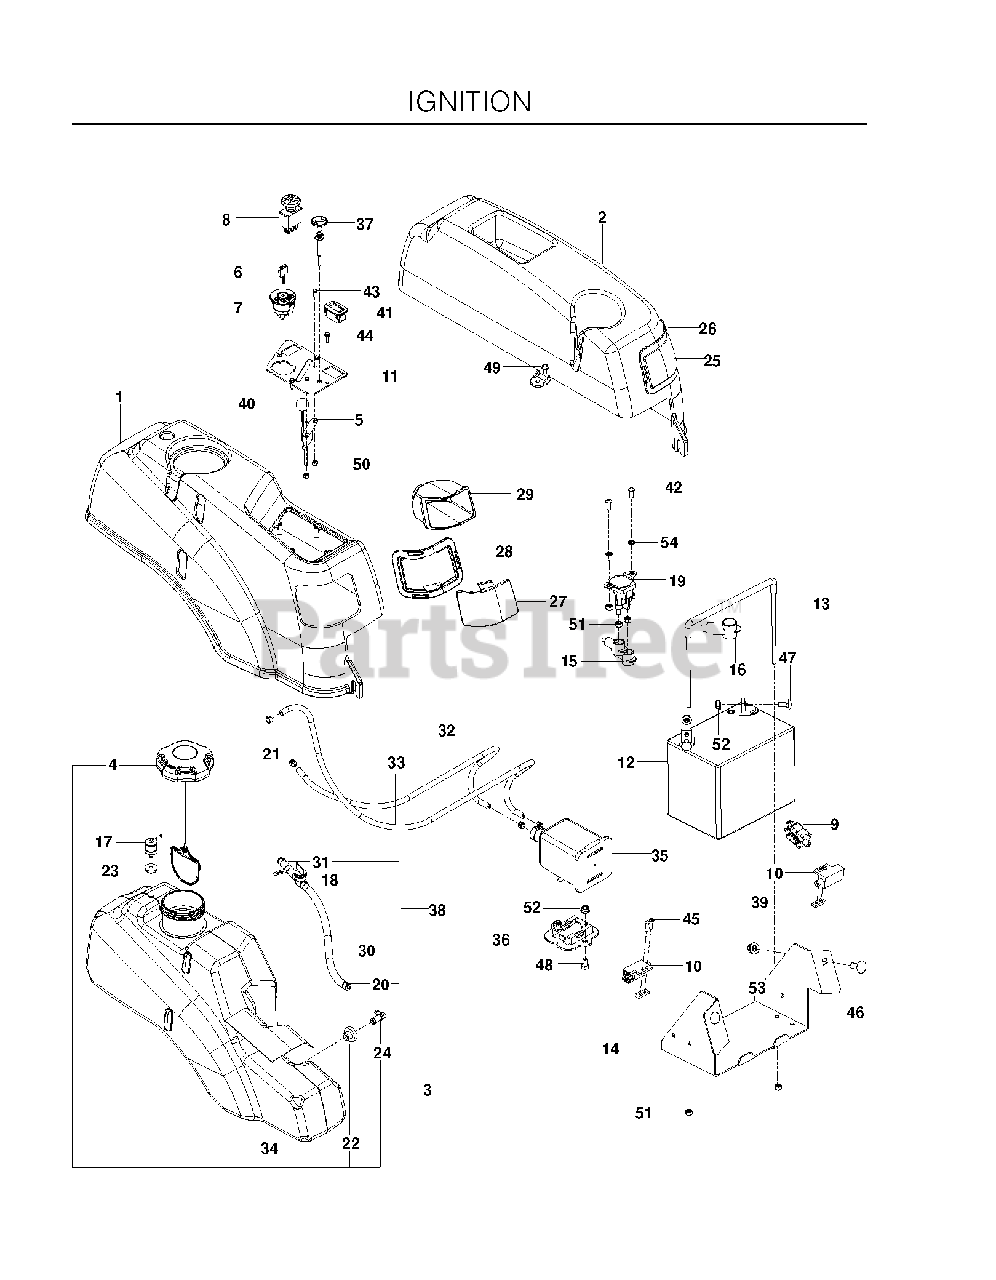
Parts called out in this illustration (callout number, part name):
2	FENDER, LT, BLK
4	CAP, FUEL
5	THROTTLE CABLE
7	IGNITION SWITCH
8	SWITCH, BLADE
9	SWITCH, BRAKE 3P
12	BATTERY, 12 V 330 AMP
13	BATTERY TIE DOWN ASSEMBLY
14	BOX, BATTERY, BLACK
15	TERMINAL COVER-SM
16	INSULATOR
17	VALVE, FUEL CHECK
18	FUEL VALVE
19	SOLENOID
20	HOSE CLAMP
21	CLAMP, HOSE
22	RUBBER GROMMET
23	GROMMET, CHECK VALVE
25	LEFT HEADLIGHT LENS
26	RING, LT BLK
27	RT HEADLIGHT LENS
28	RING, TRIM, RT-BLK
30	GAS LINE 10"
31	FUEL LINE - 2.5"
32	HOSE, VAPOR 3/16 X 30"
33	HOSE, VAPOR 3/16 X 39"
35	CANNISTER, CARBON
36	BRACKET, CANISTER
37	CHOKE CABLE
38	FUEL LINE ASSY
39	TAPPED PLATE
40	KNOB ROUND BALL
41	HOUR METER
42	SCR 1/4-20 X 5/8 BTN SKT HD ZD
43	HCS #10-24 X 1/2
44	SCR #10-12X3/4 HEX WAS HD ZD
45	SCR #10-24 X .75 SKT HD BLK
46	RHSNB 3/8C X 1
47	BOLT 5/16C X 3/4" CARRIAGE
49	BOLT 1/4-20 X 1/2 HWST
50	NUT 10-24 NYLOC
51	NUT 1/4-20 NYLOC
52	5/16-18 NYLOC FLANGE NUT
53	NUT 3/8-16 HEX FLG NYLOC ZD
54	WASHER 1/4 INT TOOTH
